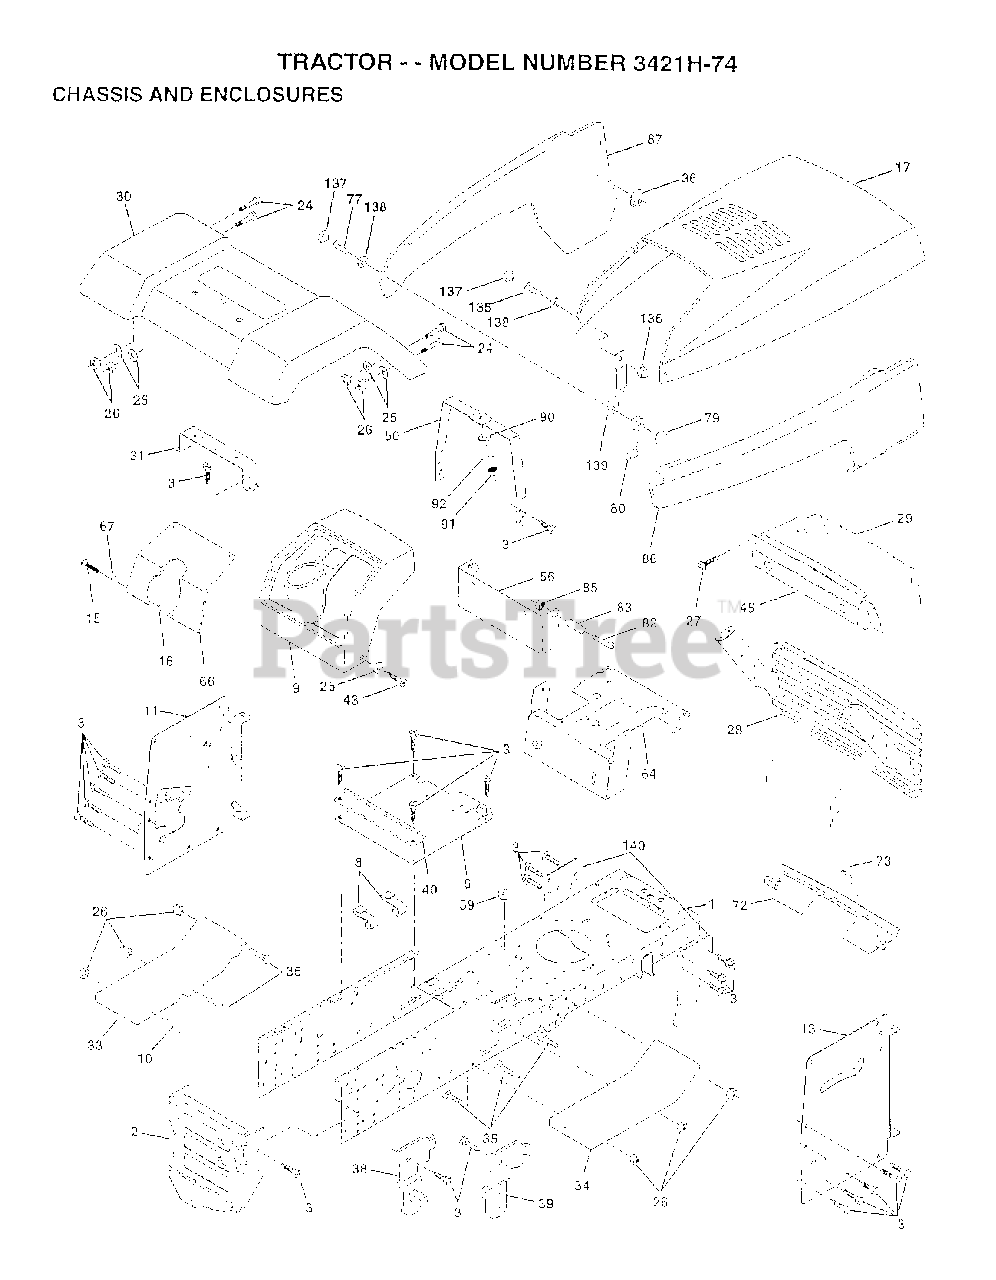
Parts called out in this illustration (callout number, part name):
6	SADDLE FLAT
8	CLIP,INSULATOR
11	PANEL DASH LT
17	Poulan TBD
25	WASHER
26	NUT
30	Poulan TBD
31	BRACKET.SUPPORT.FENDER
33	Poulan TBD
34	Poulan TBD
36	PAL NUT LT
38	BRACKET LH PIVOT
39	BRACKET RH PIVOT
43	SCREW GTV
50	DASH SUPT YP
64	DASH LOWER LT
66	Poulan TBD
67	WASHER
72	Poulan TBD
73	SCREW CRT
77	SCREW
79	NUT.WELD
80	LATCH.HOOD.
82	SCREW
83	SPACER LT
85	NUT **
86	Poulan TBD
87	Poulan TBD
90	WASHER PM
91	NUT
92	LOCKWASHER
135	SCREW 10-24X3/8
136	NUT
137	SNAP CAP LT
138	WASHER LT
139	BRACKET.SUPPORT.HOOD/PANEL.NLA
140	BRACKET SUSPENSION FRONT
